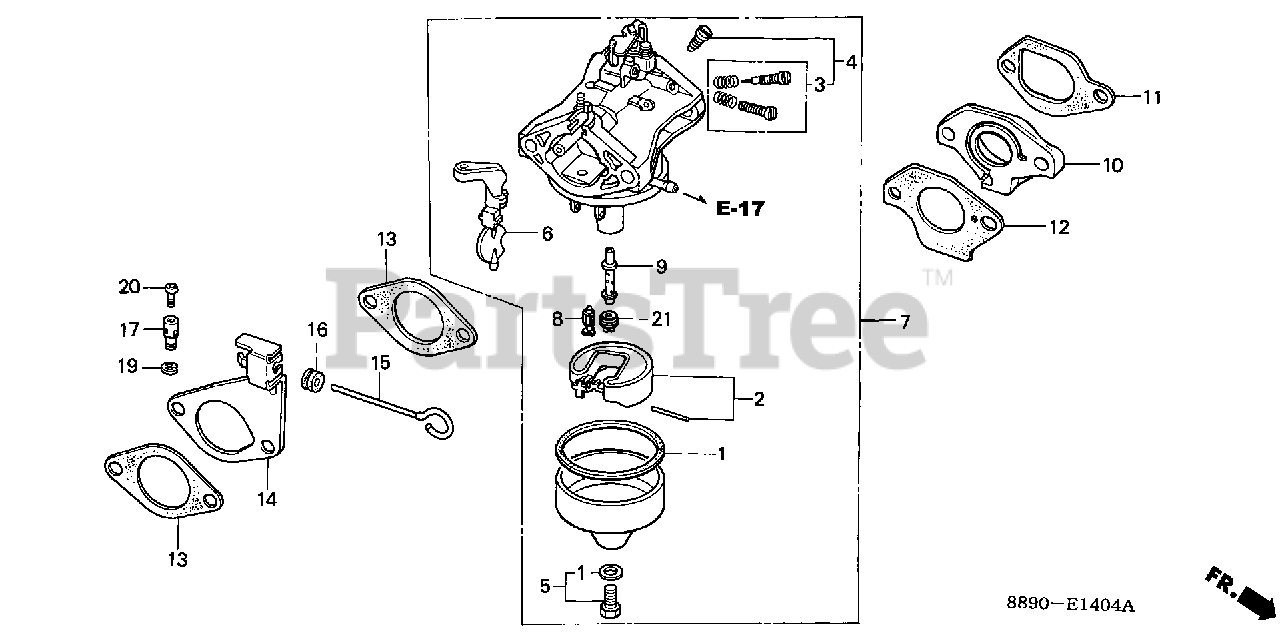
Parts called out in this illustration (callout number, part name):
1	GASKET SET
2	FLOAT SET (CARBURETOR NO.)
3	SCREW SET A
4	SCREW SET A (CARBURETOR NO.)
5	SCREW SET B (CARBURETOR NO.)
6	CHOKE SET (CARBURETOR NO.)
7	CARBURETOR ASSY. (BB33A B)
8	VALVE, FLOAT (CARBURETOR NO.)
9	NOZZLE, MAIN (CARBURETOR NO.)
10	INSULATOR, CARBURETOR
11	GASKET, INSULATOR
12	GASKET, CARBURETOR
13	GASKET, AIR CLEANER
14	STAY, CHOKE CONTROL (NOT AVAILABLE)
15	ROD, CHOKE CONTROL (NOT AVAILABLE)
16	GROMMET, CHOKE ROD
17	HOLDER, CABLE
19	CIRCLIP (5MM)
20	SCREW, PAN (4X8)
21	JET, MAIN (#75) (CARBURETOR NO.)
21	JET, MAIN (#78) (CARBURETOR NO.)
21	JET, MAIN (#80) (CARBURETOR NO.)
21	JET, MAIN (#82) (CARBURETOR NO.)
21	JET, MAIN (#85) (CARBURETOR NO.)
